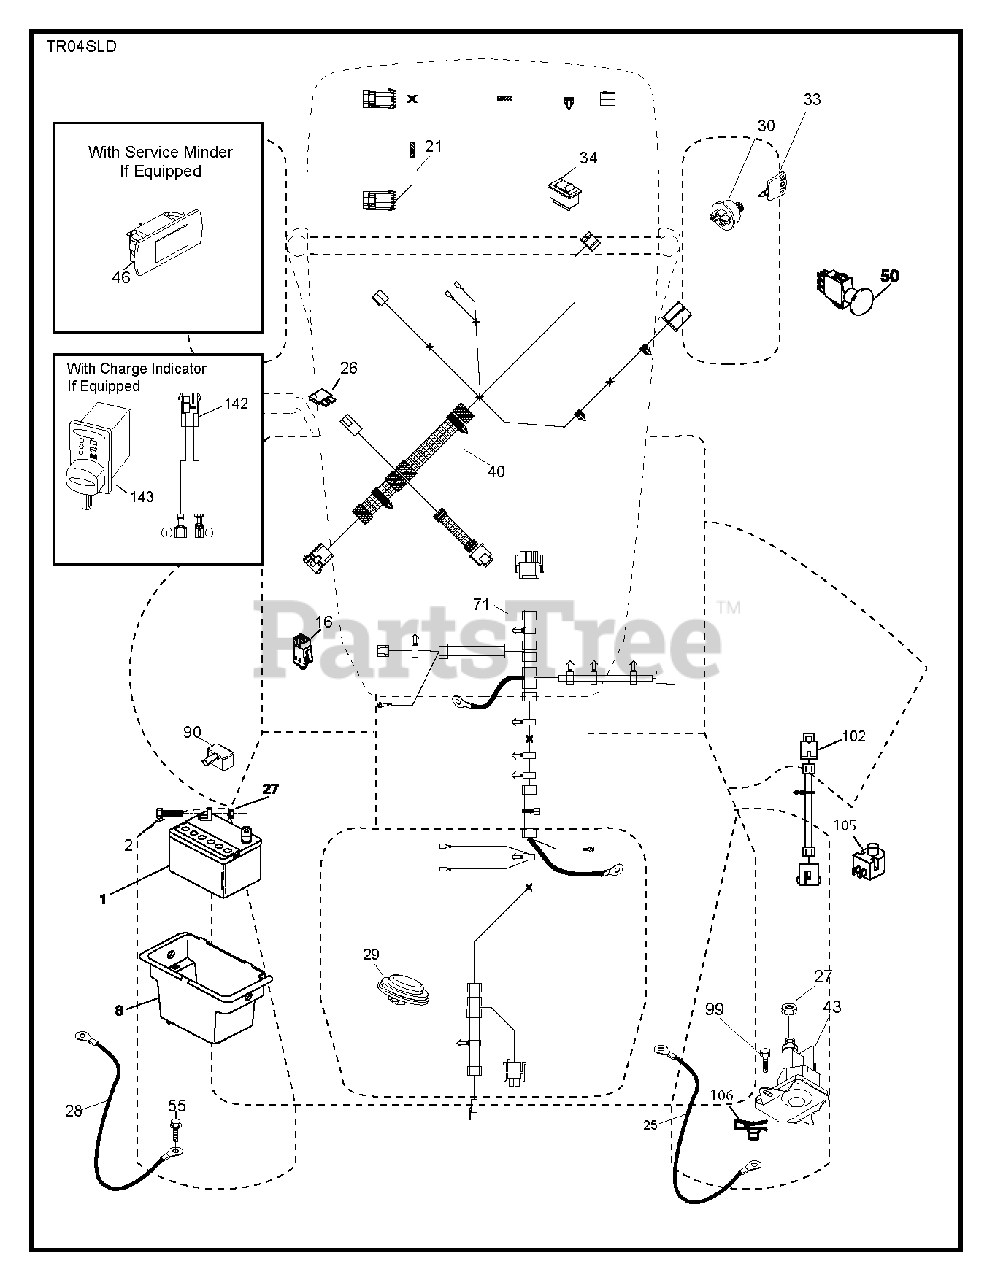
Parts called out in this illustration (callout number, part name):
1	Battery, Dry 30 Amp
2	BOLT.HEX.1/4.X.3/4.DICHROMATE
8	BOX.BATTERY.MNT.REAR.L
16	SWITCH INTERLOOK PUSH-IN
21	HARNESS LIGHT ASSY TRACTOR,
25	CABLE.BATT.RED.8GA.17
26	FUSE 20AMP
27	NUT
28	CABLE.GROUND.REAR.BATTERY.8G
29	SWITCH.SEAT.DELTA.OPC.
30	SWITCH.IGN.DELTA.W.LGH.ROS
33	KEY.CHAIN.BLISTER.PACK.GEN.INT
40	HARNESS.TEX.DASH.ELEC.REAR BAT
43	SOLENOID.STARTER.BRASS.PLUNGER
46	GUAGE.SRVCMNDR.HRMTR.
50	SWITCH.PTO.8TERMINAL.STD.BLK
55	SCREW 5/16"
71	HARNESS.CHASSIS.RRBATT.RDYSTRT
90	COVER.TERMINAL.BATTERY
99	SCREW HEXWSHR 1/4-20X3/4
102	HARNESS PIGTAIL PCH TEX ROS
105	REVERSE SWITCH
106	1/4-20 U NUT
